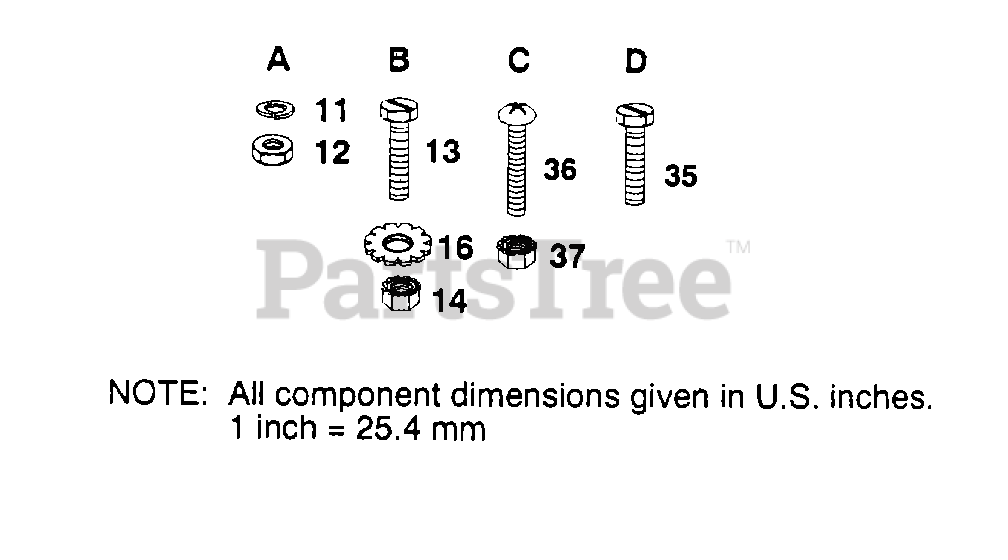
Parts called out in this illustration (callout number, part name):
12	NUT
13	BOLT
14	NUT
35	SCREW
